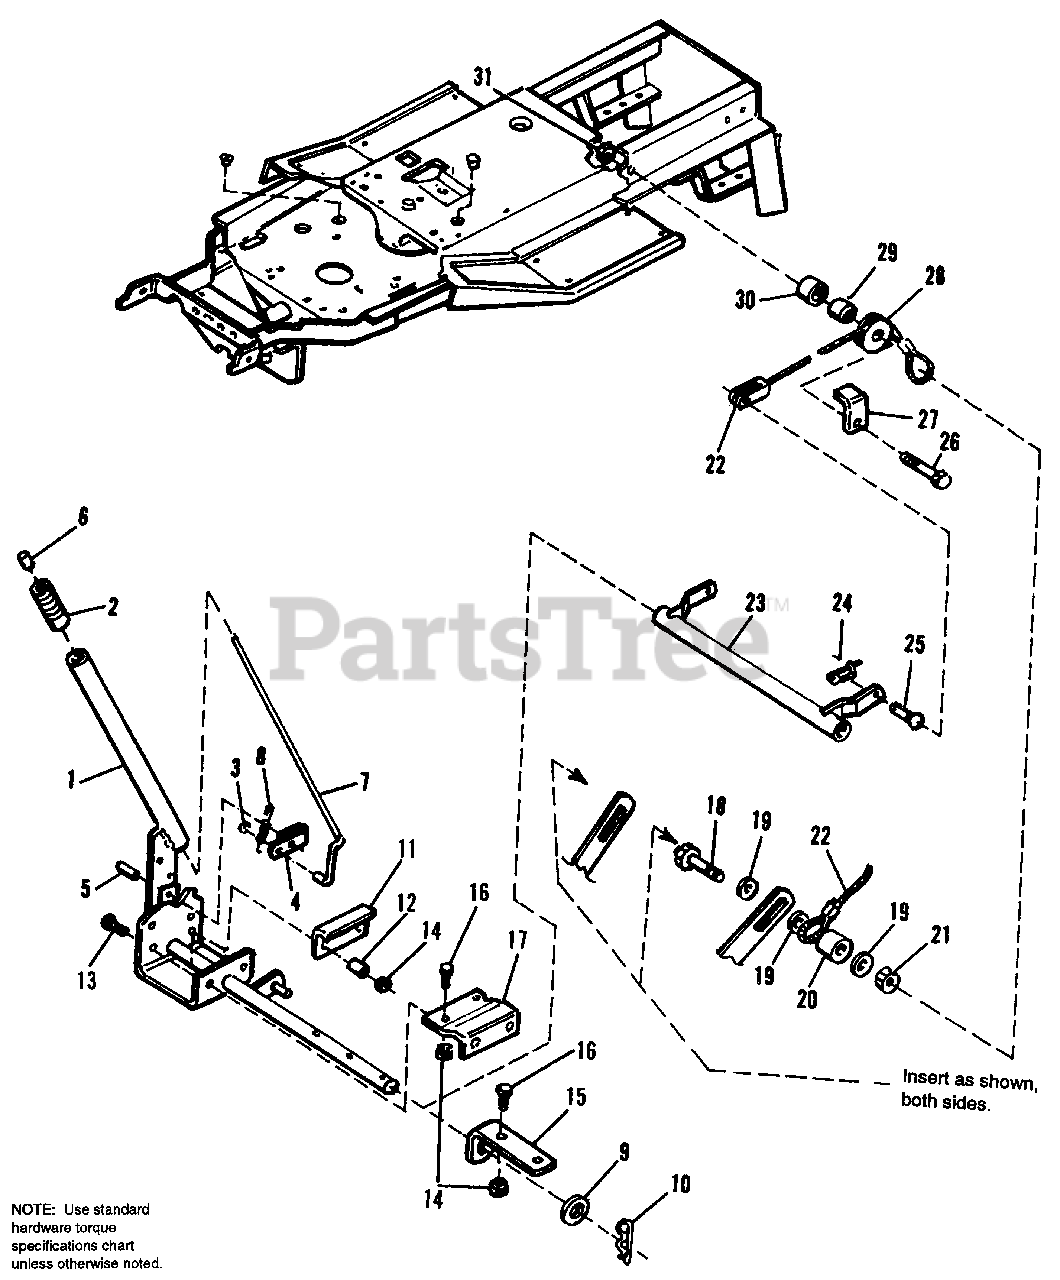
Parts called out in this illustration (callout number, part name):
1	LEVER ASSY., Lift
2	GRIP, Lift Lever
3	NUT, Push-On
4	LATCH, Lift Lever
6	BUTTON, Thumb
9	WASHER, Flat
10	CLIP, Hair Pin
11	BRACKET, Guide, Lift
13	CAPSCREW, Hex Hd., 5/16-18 x 1-1/4
14	NUT, Hex, Lock, ESNA, 5/16-18
15	BRACKET, Pivot, Lift
16	CAPSCREW, Hex Hd., 5/16-18 x 7/8
17	BRACKET ASSY., Lift Mounting
18	CAPSCREW, Hex, 5/16-18 x 1-1/2
19	WASHER, 11/32 x 7/8 x 1/16
21	NUT, Hex, Lock, ESNA, 5/16-18
22	CABLE ASSY., Lift
23	LIFT TUBE ASSY.
24	CLIP PIN
26	CAPSCREW, Hex, 3/8-16 x 2-1/2
27	GUARD, Cable
28	PULLEY, Plastic
31	NUT, Hex, Flange Lock, 3/8-16
